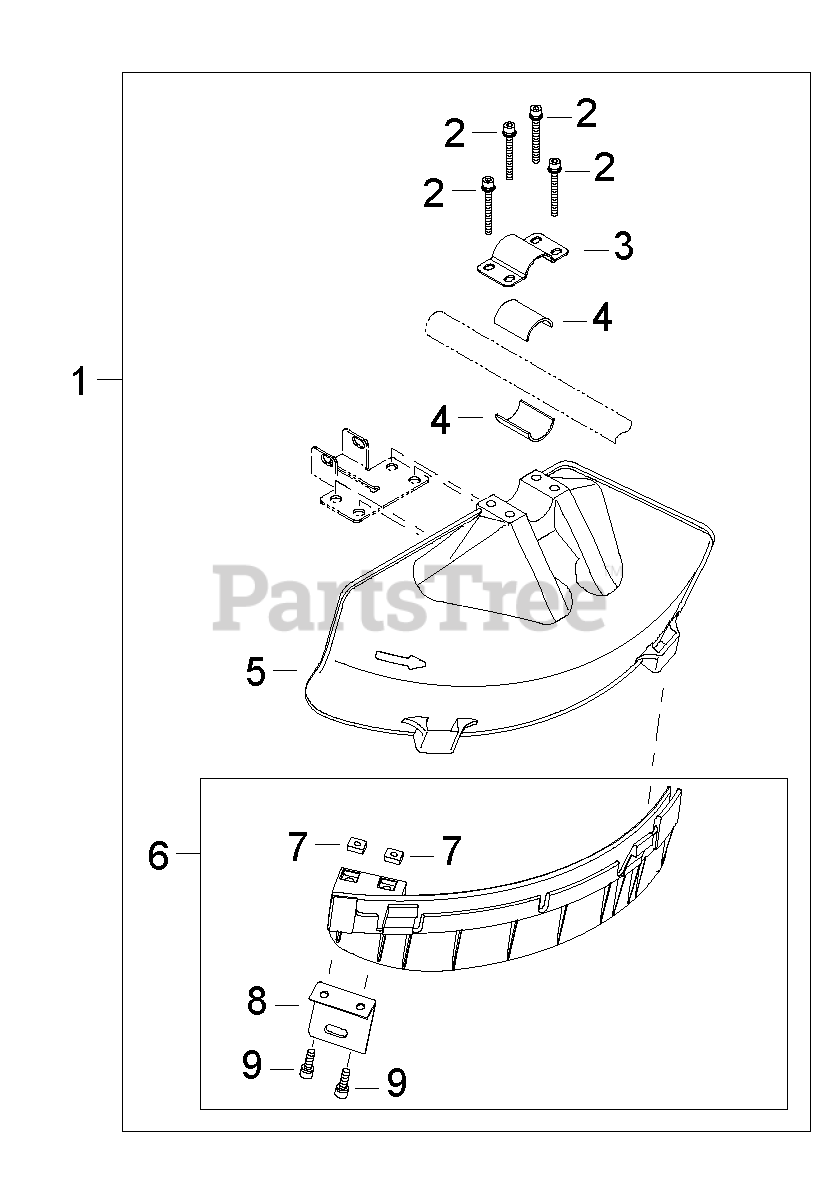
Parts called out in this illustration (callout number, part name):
1	DEBRIS SHIELD KIT
2	BOLT M5×45
3	CLAMP, UPPER
4	SPACER 26
5	SHIELD, DEBRIS PLASTIC
6	DEBRIS SHIELD EXTENSION ASSY
7	NUT M5
8	CUTTER
9	BOLT M5×16
